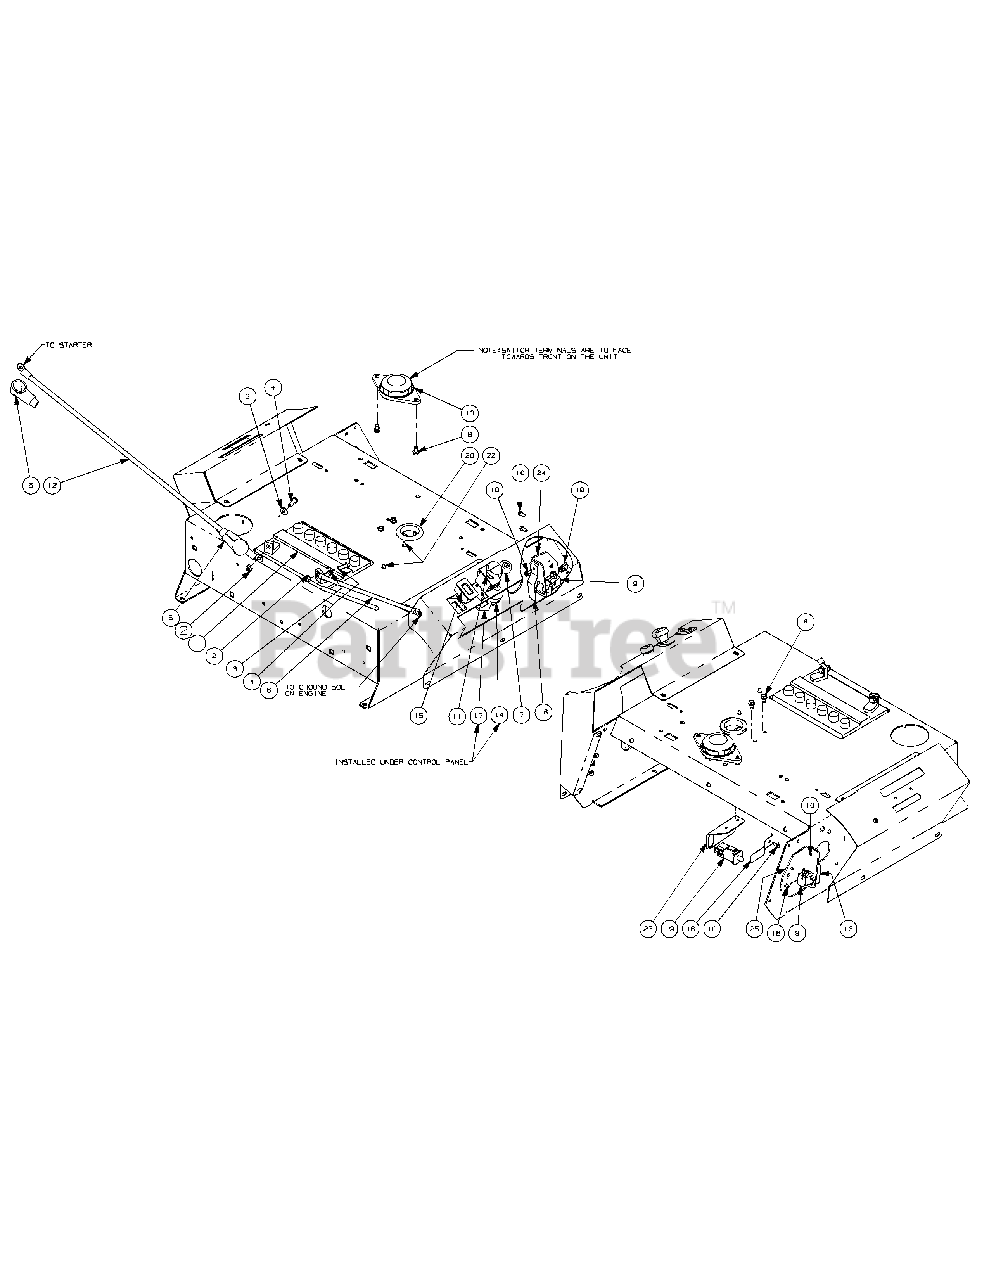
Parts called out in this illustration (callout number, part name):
1	Battery, 12V 225CCA 30Min
2	Lock Nut, Nylon Insert, 1/4-20
3	Flat Washer, 1/4
4	Hex Cap Screw, 1/4-20 x .75
5	Boot, 1" OD Rubber Battery-PST Red
6	Cable, Battery, Black, 17"
7	Nut, 5/8-32, w/Cap
8	Self Tapping Screw, 1/4-20 x 1/2
9	Normally Closed Safety Switch
10	Self Tapping Screw, 10-32 x 1/2
11	Electric PTO Switch
12	Cable, Battery, Red, 24"
13	Normally Closed Seat Switch
14	Switch, Ignition, 6 Pin
15	Hour Meter includes:
16	Safety Switch Retainer Spring
17	PTO Switch Bracket
18	U-nut, 10-24
19	Switch, Safety N.O./N.C.
20	Gromment, 1.5 ID x 2.13 OD
22	Electrical Conduit Clip, 3/8
23	Brake Switch Mounting Bracket
24	Bracket, Safety Switch, Right Hand
25	Bracket, Safety Switch, Left Hand
